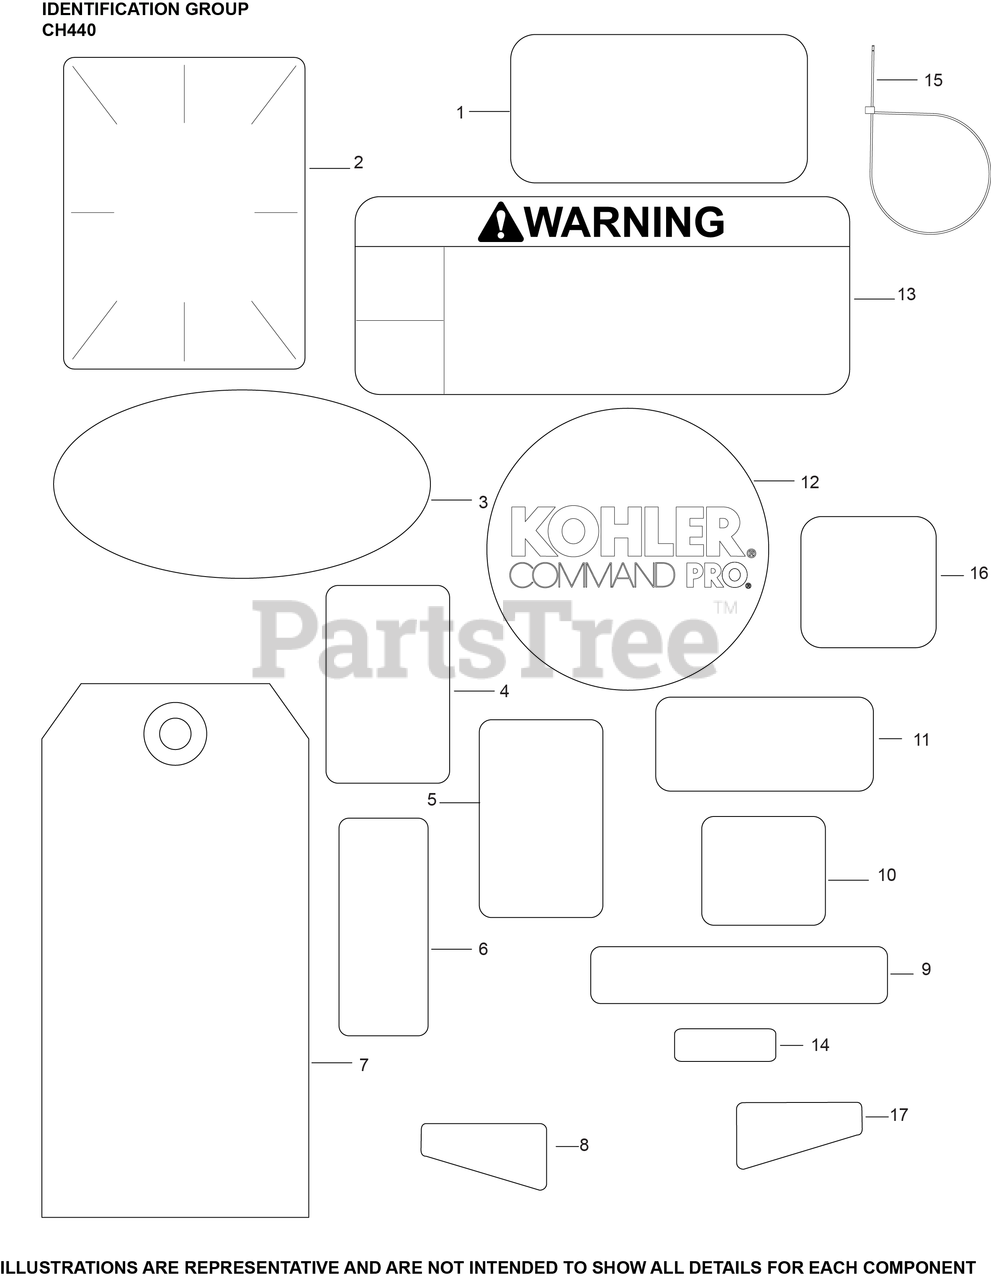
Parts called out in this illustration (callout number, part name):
1	LABEL, MAINTENANCE (CKY)
2	LABEL, CLEAR LAMINATION
3	DECAL, QUAD CLEAN SILVER
4	DECAL, SNOW FLAKE
5	DECAL, SUN
6	DECAL, FUEL/CHOKE - ON/OFF
8	DECAL, 14 HP/429cc/CH440
9	DECAL, THROTTLE
10	DECAL, BASE ARROW
11	LABEL, CANADIAN COMPLIANCE
11	DECAL, ETHANOL WARNING
12	LABEL, RECOIL 75MM
13	DECAL, WARNING
